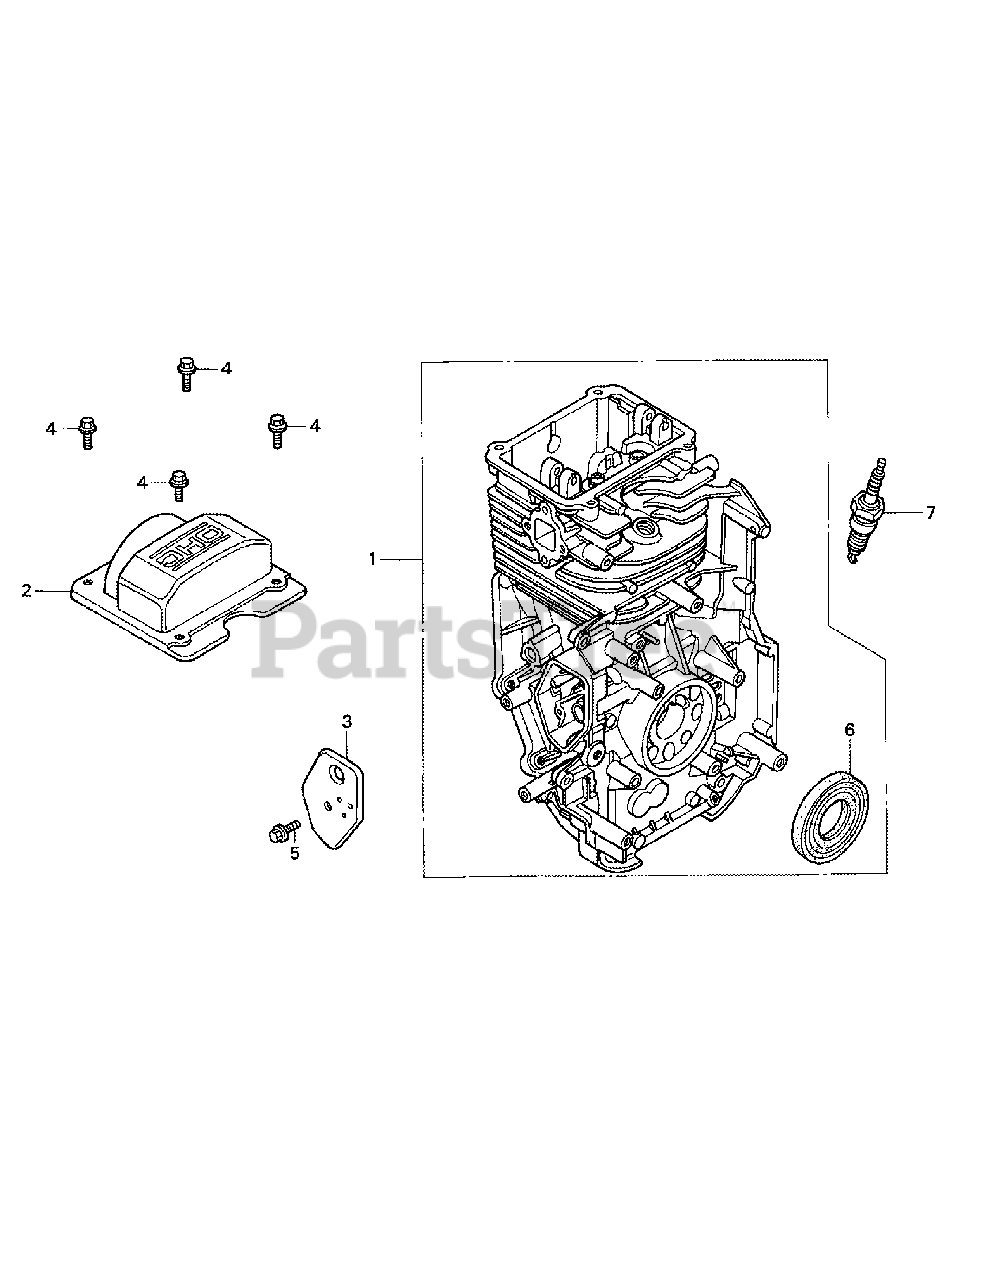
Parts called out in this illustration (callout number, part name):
1	Cylinder Assembly
2	Head Cover
3	Breather Cover
4	Flange Bolt, 6 X 12
5	Flange Bolt, 6 X 14
6	Oil Seal, 25.4 X 62 X 6
7	Spark Plug (BPR6ES NGK)
